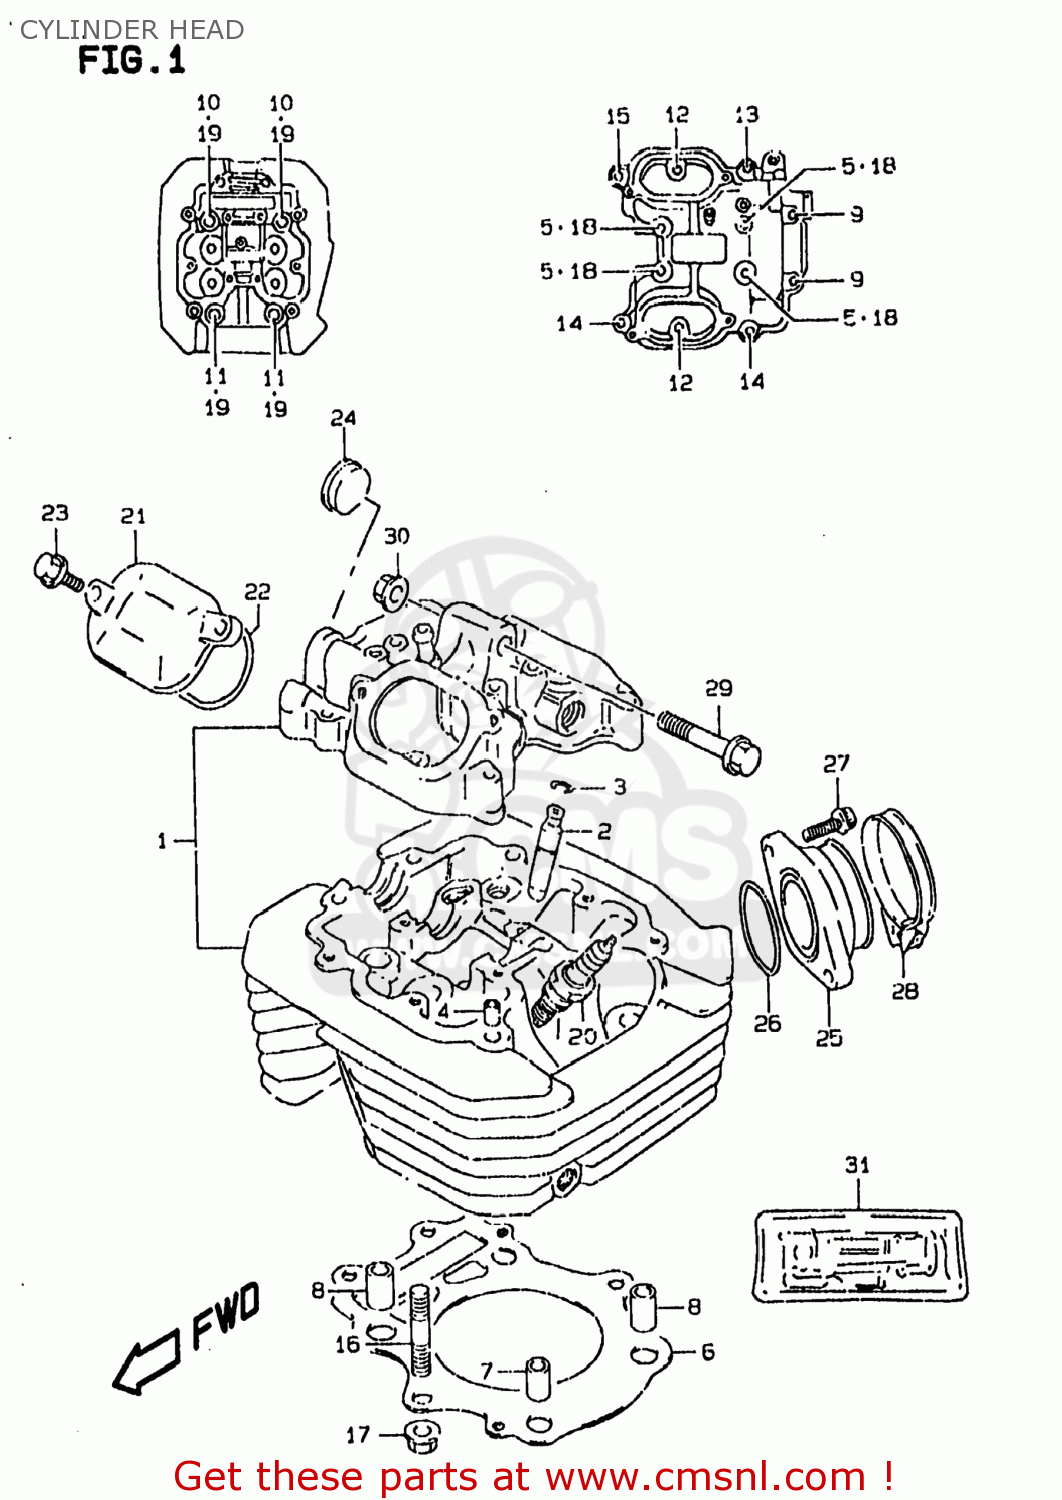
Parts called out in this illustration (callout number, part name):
1	HEAD ASSY,CYLINDER
2	GUIDE,VALVE
3	RING,SNAP
4	PIN(6.2X8X11)
5	BOLT(6X55)
6	GASKET,CYLINDER HEAD (NAS)
7	PIN
8	PIN(10.4X13X22)
9	BOLT(6X115)
10	BOLT(10X180)
11	BOLT(10X155)
12	BOLT
13	BOLT
14	BOLT(6X35)
15	BOLT(6X39)
16	BOLT,STUD
17	NUT
18	GASKET(5.8X13X1.2) (NAS)
19	WASHER (10.5X22X2.3)
20	PLUG,SPARK(CR9EK)
21	CAP,INSPECTION
22	O RING,INSPECTION CAP
23	BOLT
24	PLUG,OD:30
25	PIPE ASSY,INTAKE
26	O RING(D:2.4,ID:39.7)
27	BOLT
28	CLAMP
31	JET,AIR(1.3)
32	JET,AIR(0.6)
33	HOSE(3X5X600)
34	CLIP
35	SCREW
36	HOSE(7X11X600)
37	HOSE(4.5X8.5X600)
38	HOSE(5X8.2X600)
39	CLIP
40	CLAMP(L:45)
